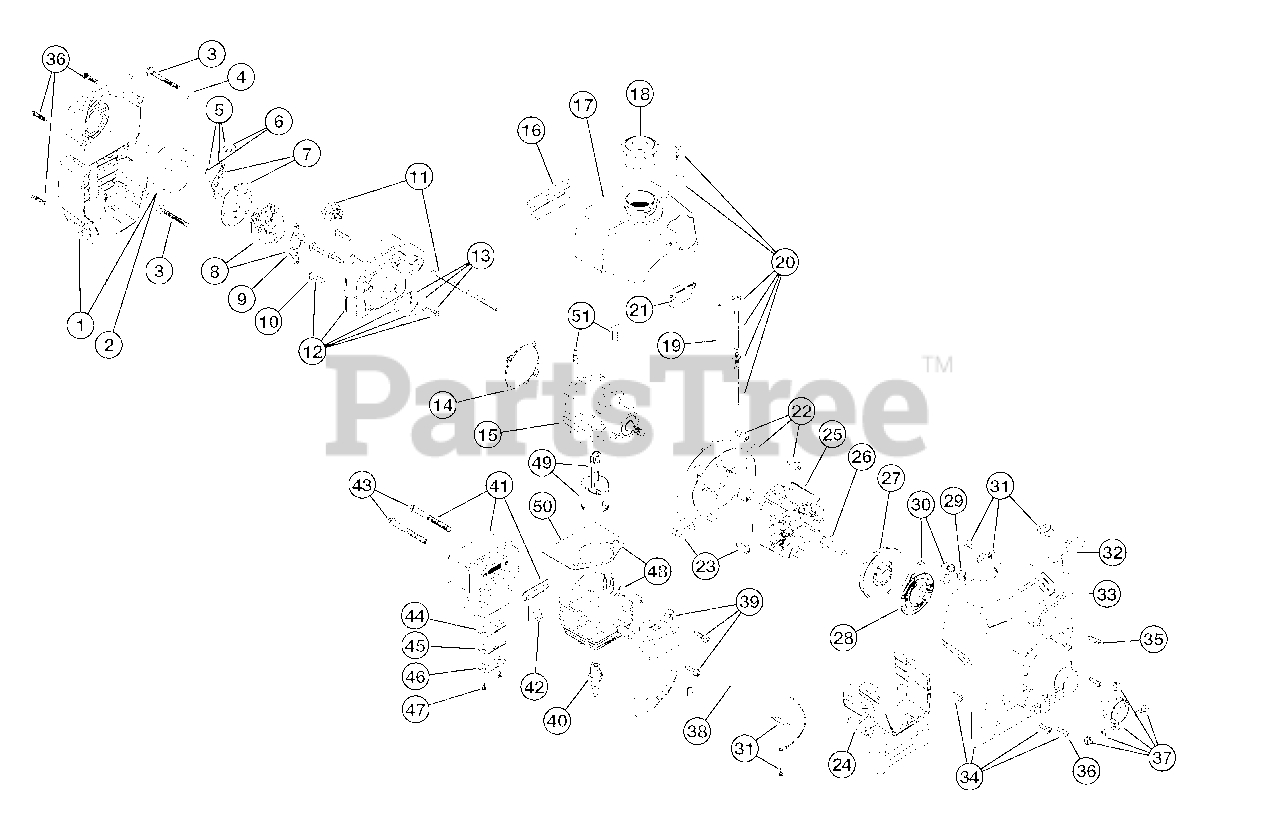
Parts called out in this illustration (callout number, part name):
1	Air Cleaner/Muffler Cover Assembly
2	Air Cleaner Filter
3	Carburetor Mounting Screws
4	Wavey Washer
5	Choke Lever Assembly
6	Choke Knob & Screw
7	Choke Lever & Plate
8	Carburetor Assembly
9	Carburetor Gasket
10	Carb Mount Screw
11	Primer and Hose Assembly
12	Carburetor Mount Assembly
13	Reed Assembly
14	Carburetor Mount Gasket
15	Crankcase Service Assembly
16	Rear Mounting Pad
17	Fuel Tank Assembly
18	Fuel Cap Assembly
19	Fuel Return Line
20	Fuel Line Assembly
21	Front Mounting Pad
22	Shroud Assembly
23	Shroud Screw
24	Shroud Extension and Stand
25	Flywheel Assembly
26	Square Nut Drive
27	Recoil Pulley
28	Recoil Spring
29	Rope Guide
30	Pulley Retainer Assembly
31	Switch Assembly
32	Pull Handle
34	Starter Housing Assembly
35	Housing Screw
36	Cover Screw
37	Upper Clamp Assembly
38	Wire Lead
39	Module Assembly
40	Spark Plug
41	Muffler Assembly
42	Exhaust Gasket
43	Muffler Mounting Bolt Assembly
44	Spark Arrestor
45	Spark Arrestor Plate
46	Spark Arrestor Hood
47	Spark Arrestor Screw
48	Cylinder Assembly
49	Piston and Rod Assembly
50	Cylinder Gasket
51	Cylinder Bolt
